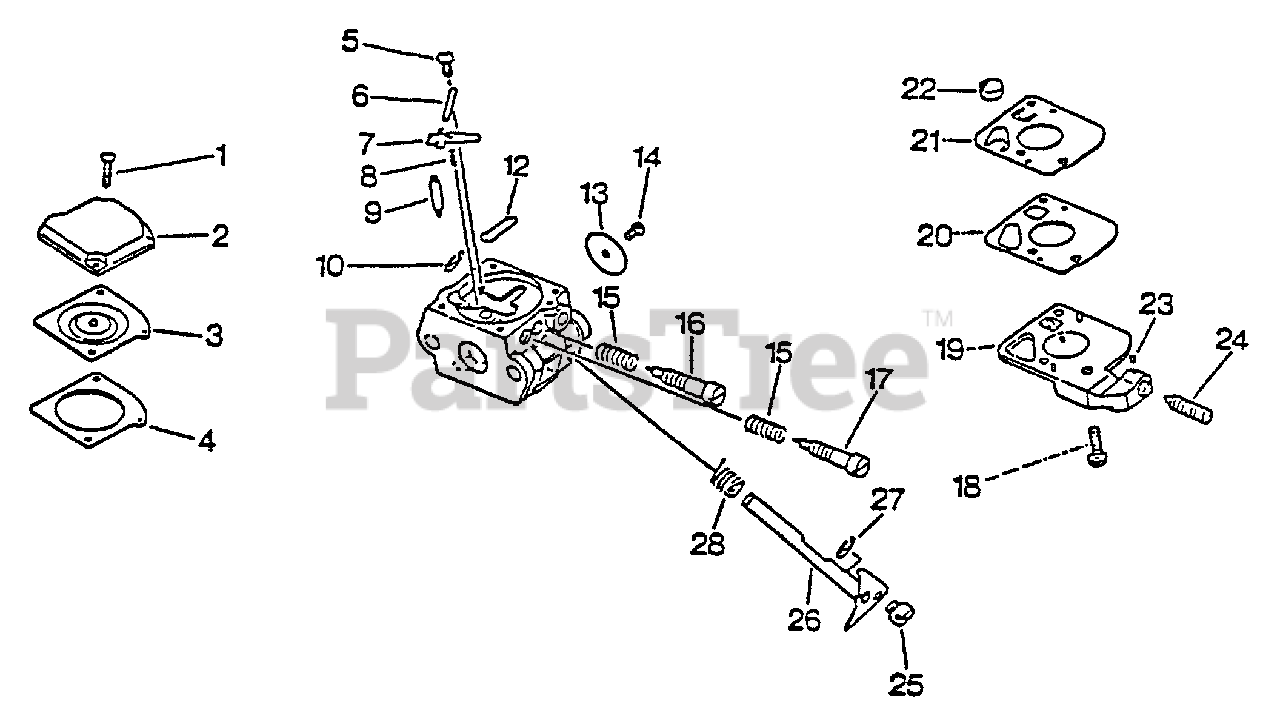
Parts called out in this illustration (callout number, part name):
2	COVER, DIAPHRAGM
3	DIAPHRAGM
4	GASKET, DIAPHRAGM
6	PIN, METERING LEVER
7	LEVER, METERING
8	SPRING
9	VALVE, NEEDLE
11	NOZZLE, CHECK VALVE
12	PLUG, WELCH
13	VALVE, THROTTLE
14	SCREW
15	SPRING, NEEDLE
16	NEEDLE, HIGH SPEED
17	NEEDLE, LOW SPEED
19	COVER, PUMP
20	GASKET, PUMP
21	DIAPHRAGM, PUMP
22	STRAINER
23	PIECE, FRICTION
24	SCREW, IDLE ADJUST
26	SHAFT, THROTTLE
28	SPRING, THROTTLE RETURN
